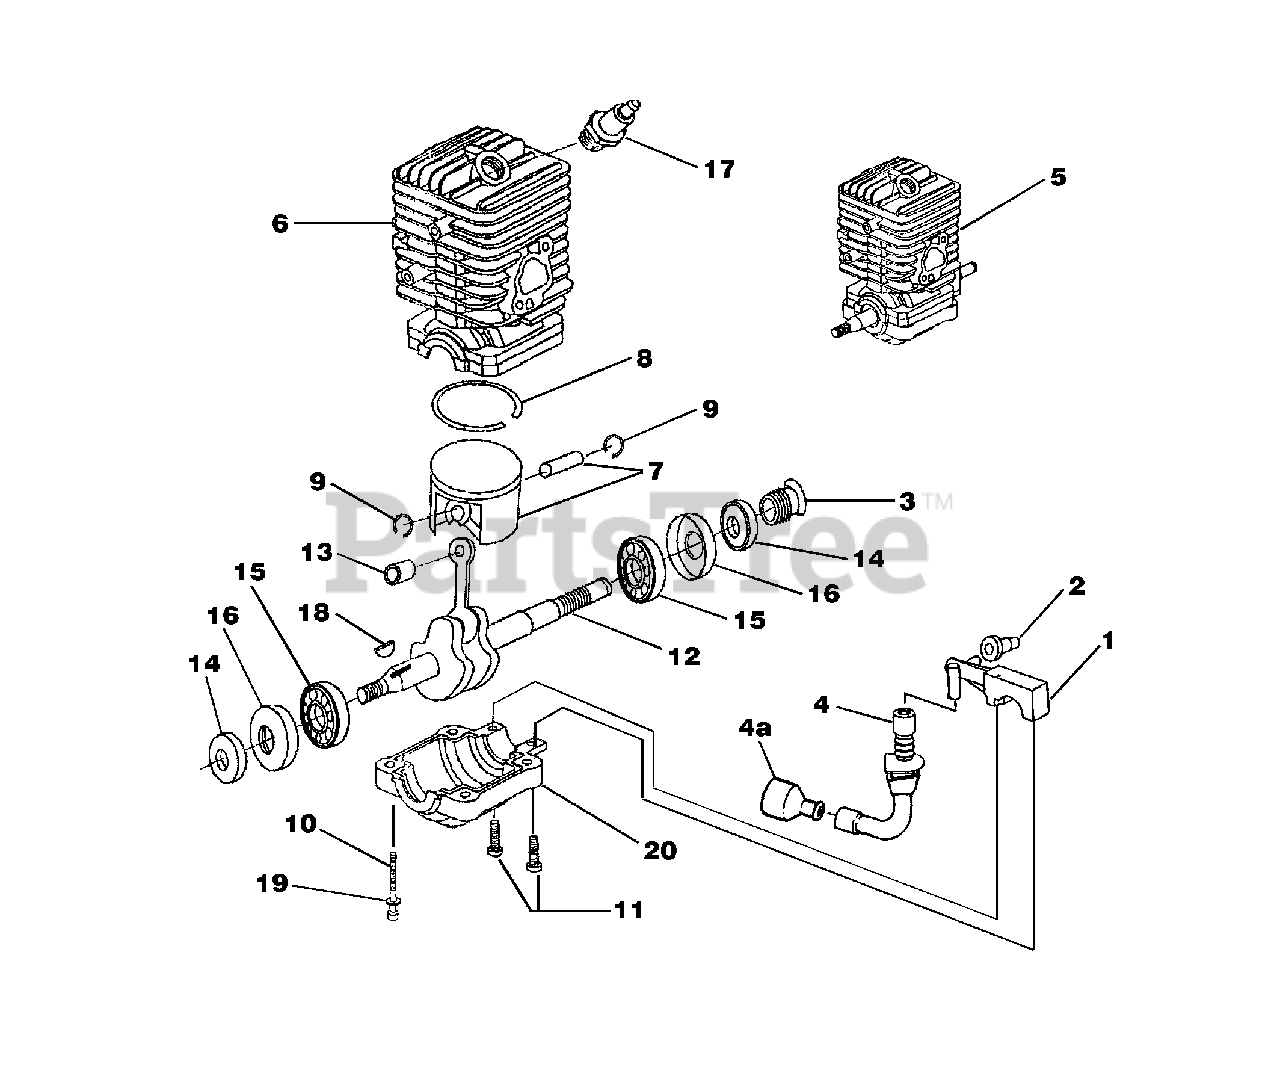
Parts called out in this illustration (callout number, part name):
1	Oil Pump Kit
2	Grommet, Oil Outlet
3	Left Hand Worm
4	Tube, Oil Intake
4A	Oil Filter
5	Short Block
6	Cylinder Kit
7	Piston & Pin
8	Piston Ring
9	Ring, Retaining
10	Screw, Cap-Socket Hd. (10-24 x 2")
11	Screw, Pan Hd., Plastite (8-16 x 5/8")
12	Crankshaft & Rod Assy
13	Bearing, Needle
14	Shaft Seal
15	Bearing & Rubber Case
16	Rubber Case
17	Spark Plug
18	Woodruff Key
19	Washer
20	Lower Crankcase
